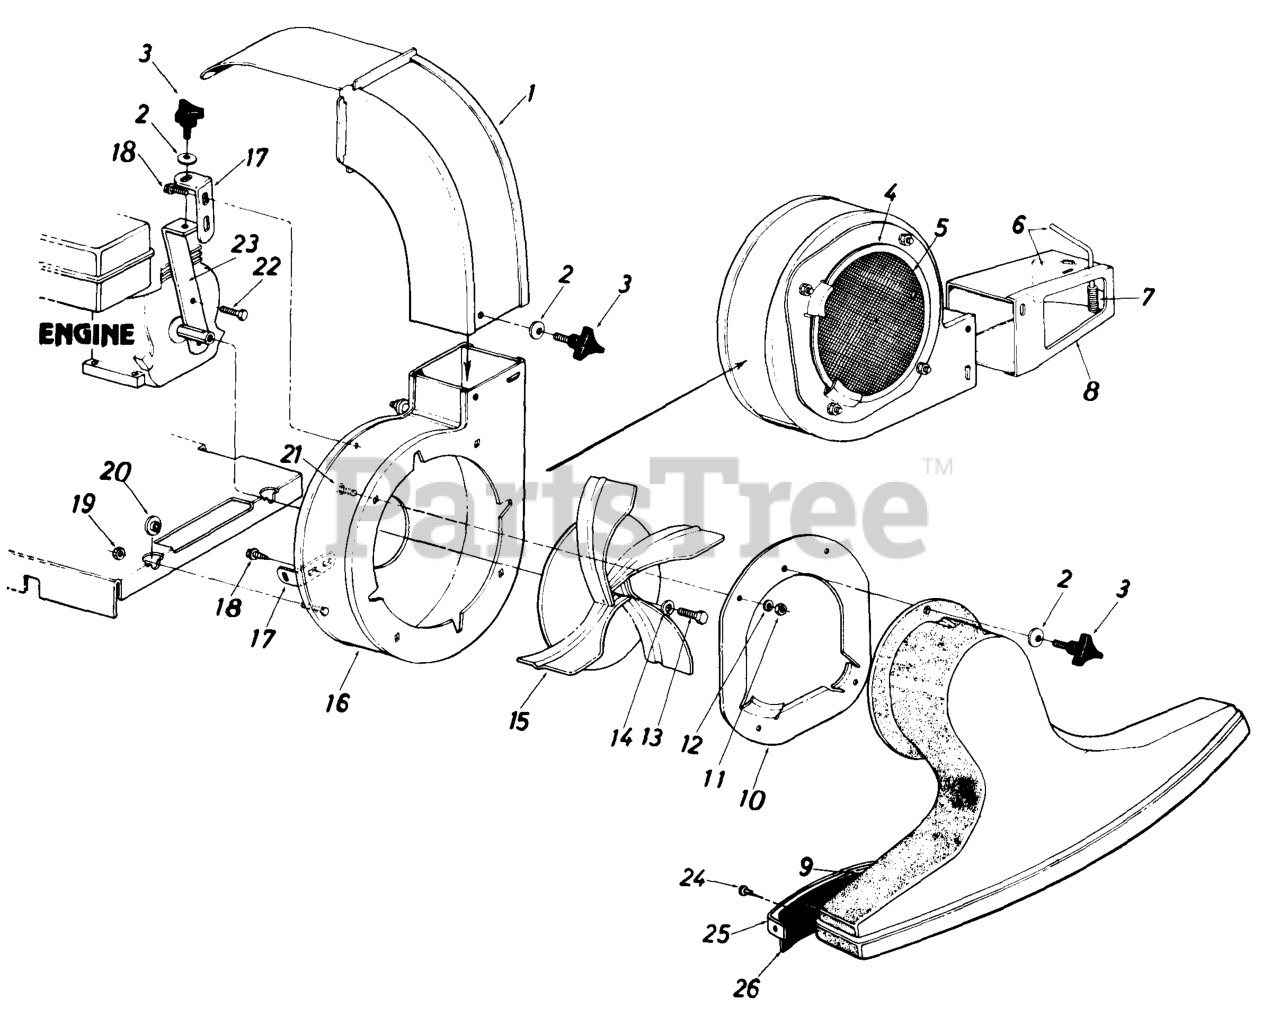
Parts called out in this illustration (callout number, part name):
3	3-Arm Thumb Scr. 5/16-18 x .75" Lg.
4	Trim Strip 36.5" Lg.
5	Impeller Guard
6	Door Assembly
7	Compression Spring
8	Directional Discharge Ass'y.
9	Nozzle Ass'y.
10	Nozzle Plate Ass'y.
11	Hex Nut 5/16-18 Thd.
12	L.-Wash. 5/16" I.D.
13	Hex Bolt 3/8-24 x 1.25" Lg.
14	L.-Wash. 3/8" I.D. H.D.
15	Air Vane Plate Ass'y. w/pulley
16	Blower Housing Complete
19	Hex Cent. L.-Nut 5/16-18 Thd.
20	Shoulder Spacer .50" I.D. x .135
21	Carriage Bolt 5/16-18 x .62" Lg.
22	Hex Locking Bolt 5/16-24 x .62" Lg.
